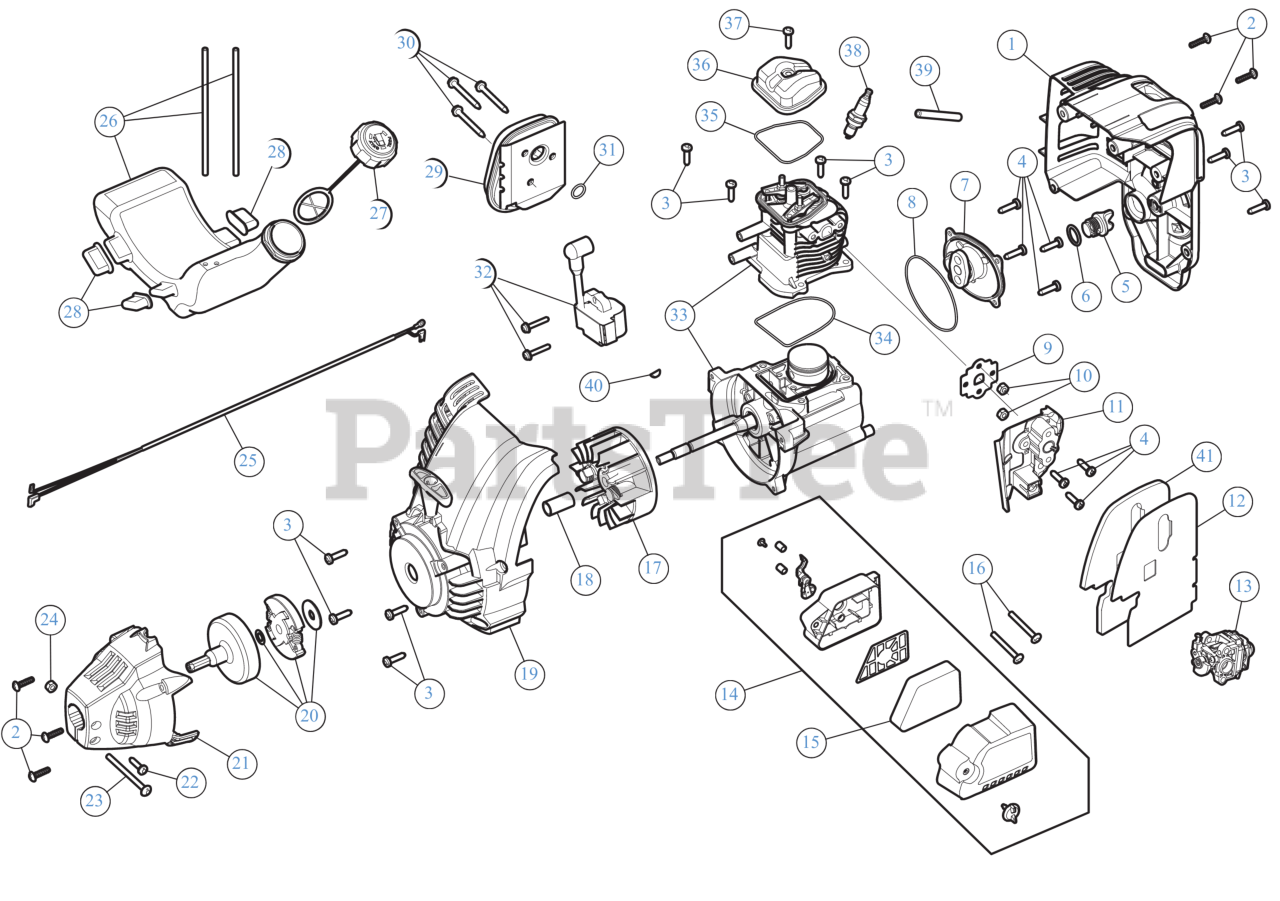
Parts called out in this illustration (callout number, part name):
1	ENGINE COVER ASSEMBLY RR
2	SCREW 8-16 x 3/4
3	SCREW M5-0.8 x 19
4	SCREW, M5 X18
5	OIL PLUG
6	RING, OIL PLUG (AC
7	CRANKCASE COVER
8	O-RING CRNKCSE CVR
9	GASKET/INSULATOR
10	NUT 10-32
11	CARB INSULATOR
12	GASKET
13	CARBURETOR
14	AIR CLEANER COVER
15	AIR FILTER
16	SCREW 10-32X2.5
17	FLYWHEEL ASSEMBLY AC3.1
18	SPACER :2.165"
19	STARTER HOUSING
20	CLUTCH ASSEMBLY
21	CLUTCH COVER ASSEMBLY
22	SCREW 8-18X.375 T-20
23	SCREW
24	HEX NUT
25	WIRE LEAD
26	FUEL TANK ASSEMBLY
27	FUEL CAP ASSEMBLY 43MM-6 W/O HOLE
28	FUEL TANK PADS
29	MUFFLER ASSEMBLY
30	SCREW M5 x 44MM
31	GASKET/MUFFLER
32	MODULE ASSEMBLY
33	SHORT BLOCK
34	O-RING CYL AC5
35	O-RING
36	ROCKER COVER
37	SCR, VALVE COVER
38	SPARK PLUG 4 CYCL
39	BREATHER HOSE
40	WOODRUFF KEY #403-.125 x .375
41	HEAT SHIELD
